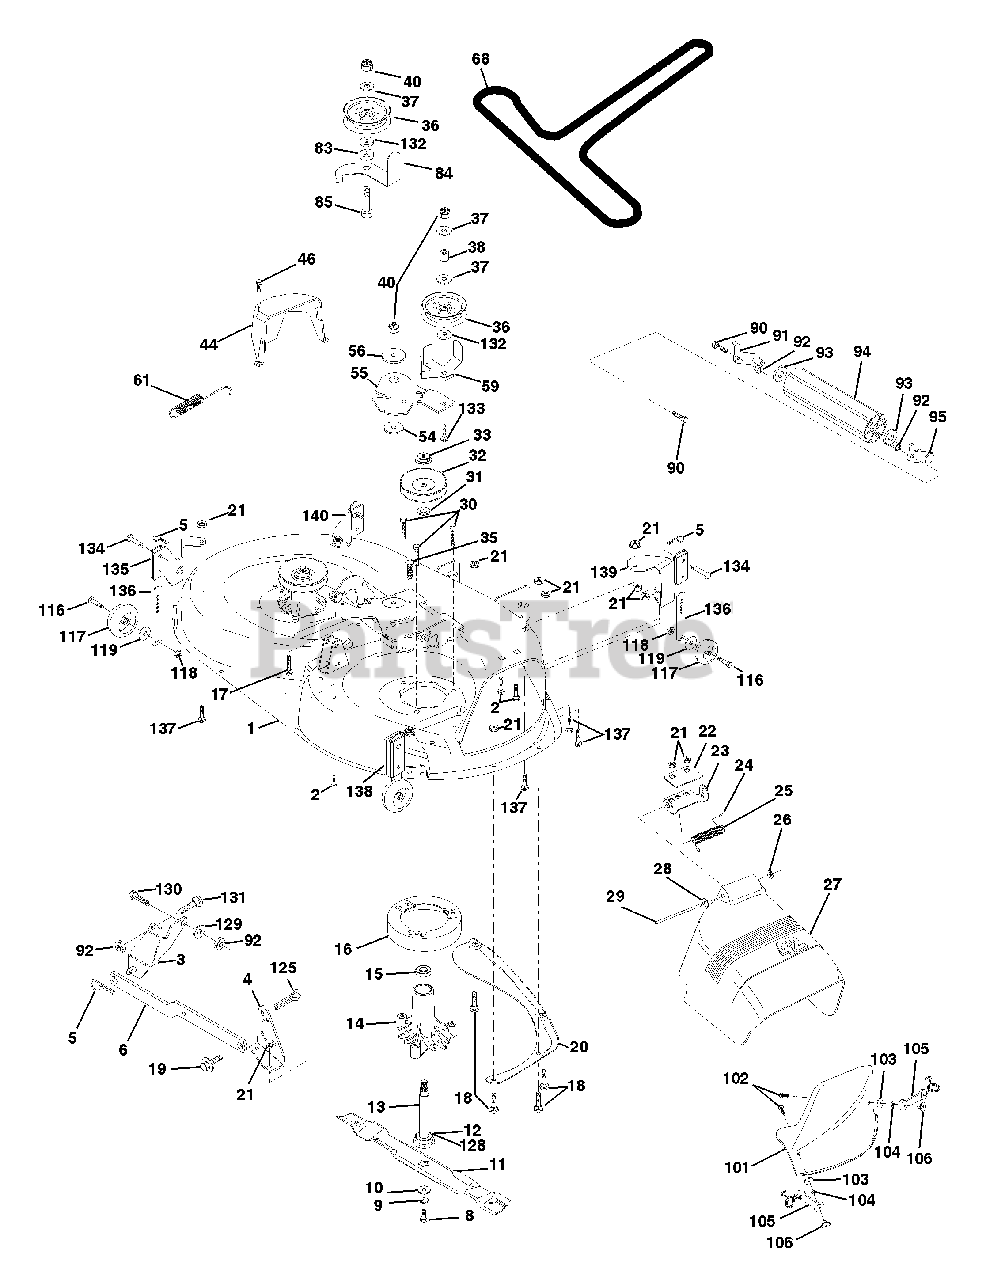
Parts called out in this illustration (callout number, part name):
1	Housing Asm Mower 42" 94 T-Path
2	Bolt Rdhd Sqnk 5/16-18unc X 3/4
3	Bracket Asm Fr Sway Bar 38/42
4	Bracket Asm Deck 42" sway Bar
5	Retainer Spring
6	Arm Suspension Rear
8	Bolt 3/8-24 x 1 25 Gr8 Patched
9	Washer Lock Hvy 3/8 Unplated
10	Washer Hard Blade Mower Vented
11	Blade Mower Mulching 42"
12	Bearing Ball #6204 (Mandrel)
13	Shaft Asm W/lower Bearing
14	Housing Mandrel Vented(machd)
15	Bearing Ball Mandrel
16	Stripper Round Mower
17	Bolt Rdhd Sqnk 3/8-16 X 2-1/4
18	Bolt Carr 5/16-18 X 5/8
19	Bolt Shoulder
20	Baffle Vortex 42 Heavy Duty
21	Nut Crown Lock 5/16-18
22	Stiffener Bracket 42" deck
23	Bracket Deflector Mower 42"
24	Cap Sleeve 80 x 112 Blk Mower
25	Spring Torsion Deflector 2 52
26	Nut Push Phos & Oil
27	Shield Deflector Mower 42" Blk
28	Washer 11/32 X 5/8 X 16 Ga
29	Rod Hinge 42" 6 75 Wlg
30	Screw Thdrol Washer Head
31	Washer Spacer Mower Vented
32	Pulley Mandrel 42"
33	Nut 9/16 top Lock Flng Cntr
35	Fastner Christmas Tree
36	Pulley Idler Flat 3 060
37	Washer 13/32 X 13/16 X 16 Ga
38	Spacer Spring Stop Idler
40	Nut Lock 3/8-16 Unc
44	Guard Mandrel LH Black
46	Screw Thdrol 1/4-20 x 5/8
54	Washer Hardened
55	Arm Idler 42" mower LT/YT
56	Spacer Retainer Pm Mower
59	Guard, Belt
61	Spring Ext. Elect
68	V-Belt Mower
83	Washer Sintered
84	Keeper Belt Idler
85	Bolt Carriage 3/8-16 x 2-1/4 Gr.5
90	Bolt Fin Hex 3/8-16 unc X 1
91	Bracket Asm Noseroller LH
92	Nut Lock Hex w/ins. 3/8-16 UNC
93	Washer 17/32 X 7/8 X 16 Ga
94	Roller Nose 38 & 42
95	Bracket Asm Noseroller RH
101	Cover Mulching 42" Blk
102	Screw
103	Washer #10
104	Washer Lock #10
105	Latch Asm Bagger
106	Nut Weld .327/.304 #10-24
116	Bolt Shld
117	Wheel Gauge Donut
118	Nut Centerlock 3/8-16 UNC
119	Washer 3/8 x 7/8 x 14 Ga.
125	Cotter Pin
128	Washer Felt
129	Washer 13/32 x 13/16 x 12 Ga.
130	Bolt Fin Hex 3/8-16 unc x 1 Gr.5
131	Bolt RdHd Sqnk 3/8-16 UNC
132	Washer 13/32 x 1-3/8 x 3 Ga.
133	Bolt RdHd 3/8-16 UNC x 2-3/4 Gr.5
134	Pin Head Rivet
135	Bracket Asm Whl Ga. Rear LH 42"
136	Bar Pnt Adjusting Wheel Gauge
137	Bolt Carriage 5/16-18 x 5/8 Short
138	Bracket Asm. Whl Ga. Rear RH 42"
139	Bracket Asm. Whl Ga. Front RH 42"
140	Bracket Asm. Whl Ga. Front LH 42"
